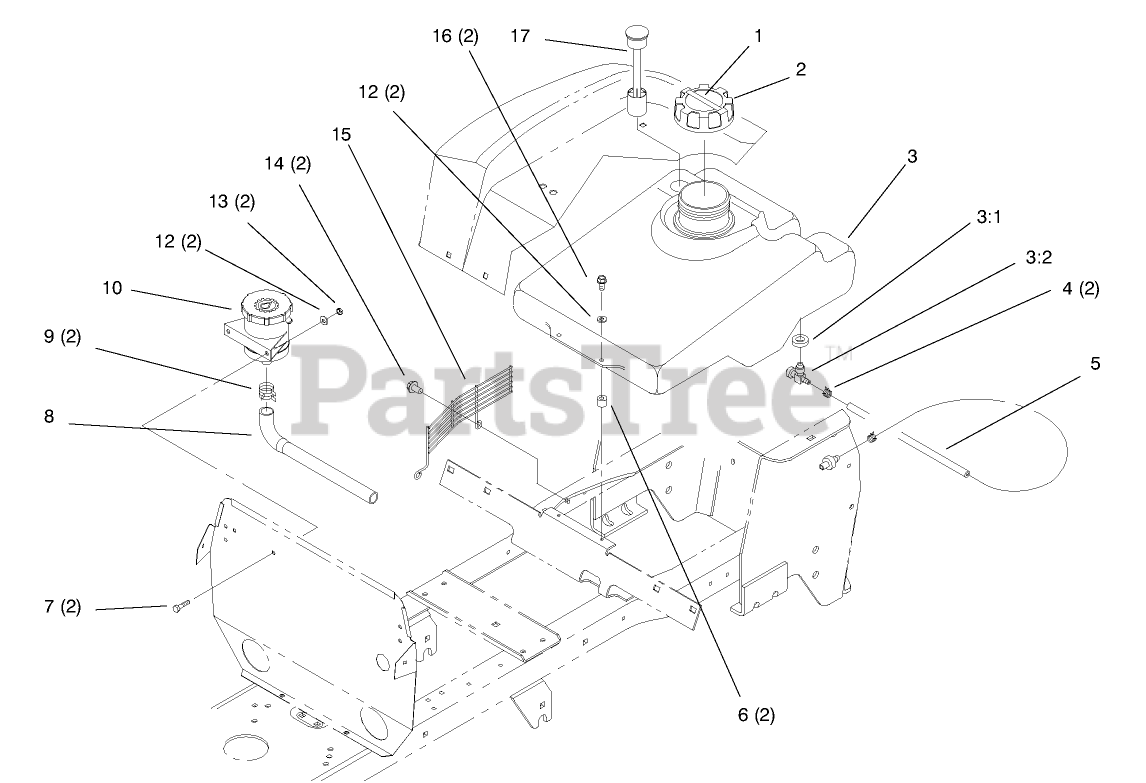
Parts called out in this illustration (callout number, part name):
2	GAS CAP ASM
3	TANK-GAS (FG50538)
3:2	VALVE-FUEL
4	CLAMP-HOSE
5	HOSE-FUEL
16	SCREW-HWH
